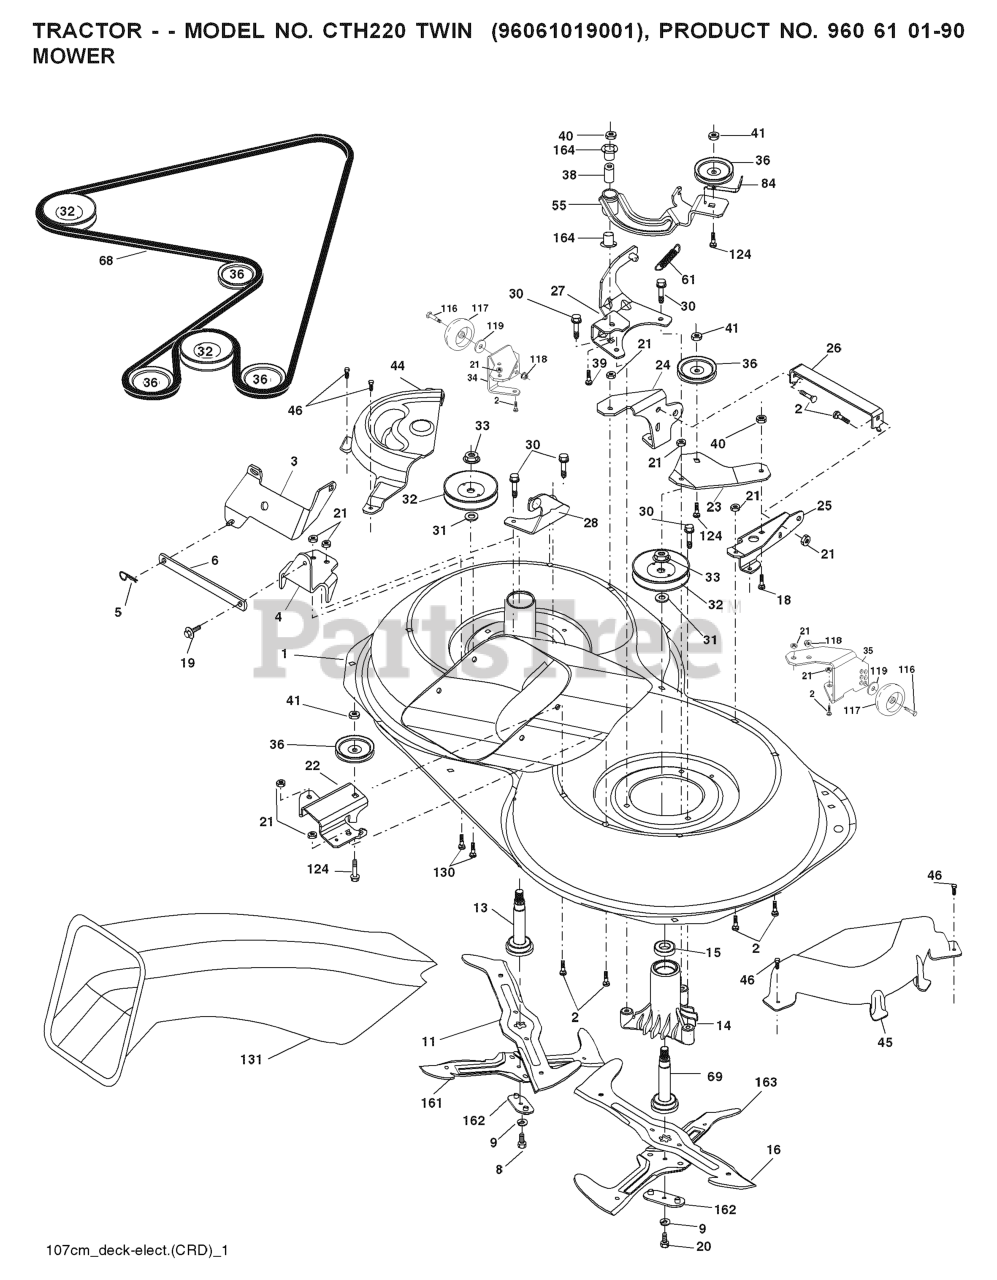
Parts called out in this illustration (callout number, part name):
1	Housing Asm. Mower 107 CRD
2	RP BOLT 5/16-18 X3/4 ZN/YEL GR
5	RETAINER-SPRNG RB
6	BAR.SWAY.92.CRD
8	BOLT.3/8-24X1.25 GR8
9	LOCKWASHER
11	BLADE.3N1.LH.CRD
13	SHAFT ASM VENT
14	HOUSING.MANDREL.VENTED (MACHD)
16	BLADE.3N1.RH.CRD
19	BOLT SHD 5/16-18
20	BOLT.3/8-24X1.25GR8. LHTHRD
21	LOCKNUT
22	BRACKET.IDLER.RR.107.CRD
25	BRACKET RF
26	SUPPORT
28	BRACKET
30	SCREW, WASHER HEAD
31	WASHER.SPACER.MANDREL
33	NUT.FLANGE.LOCK.TOP
34	BRACKET
35	BRACKET
36	PULLEY.IDLER.4.25
41	NUT LOCK FLG 3/8-16 UNC
45	COVER.MANDREL.RH.CRD
46	SCREW.1/4-20X5/8
55	ARM.IDLER.107.CRD
68	HEX-BELT 107 MOWER
69	SHAFT.ASM.W/LWR.BRG.RH.THREAD
84	KEEPER, BELT IDLER
116	BOLT.SHOULDER.3/8-16X3-5/8.
117	RP WHEEL. GUAGE RALLY
118	NUT LOCK FLG 3/8-16 UNC
119	WASHER
124	BOLT.3/8-16X1.50
130	BOLT.CARR.SQNK.5/16-18UNC.X3/4
131	CHUTE BAGGER
163	BLADE.CROSS.RH.CRD.107
164	BRNG T
